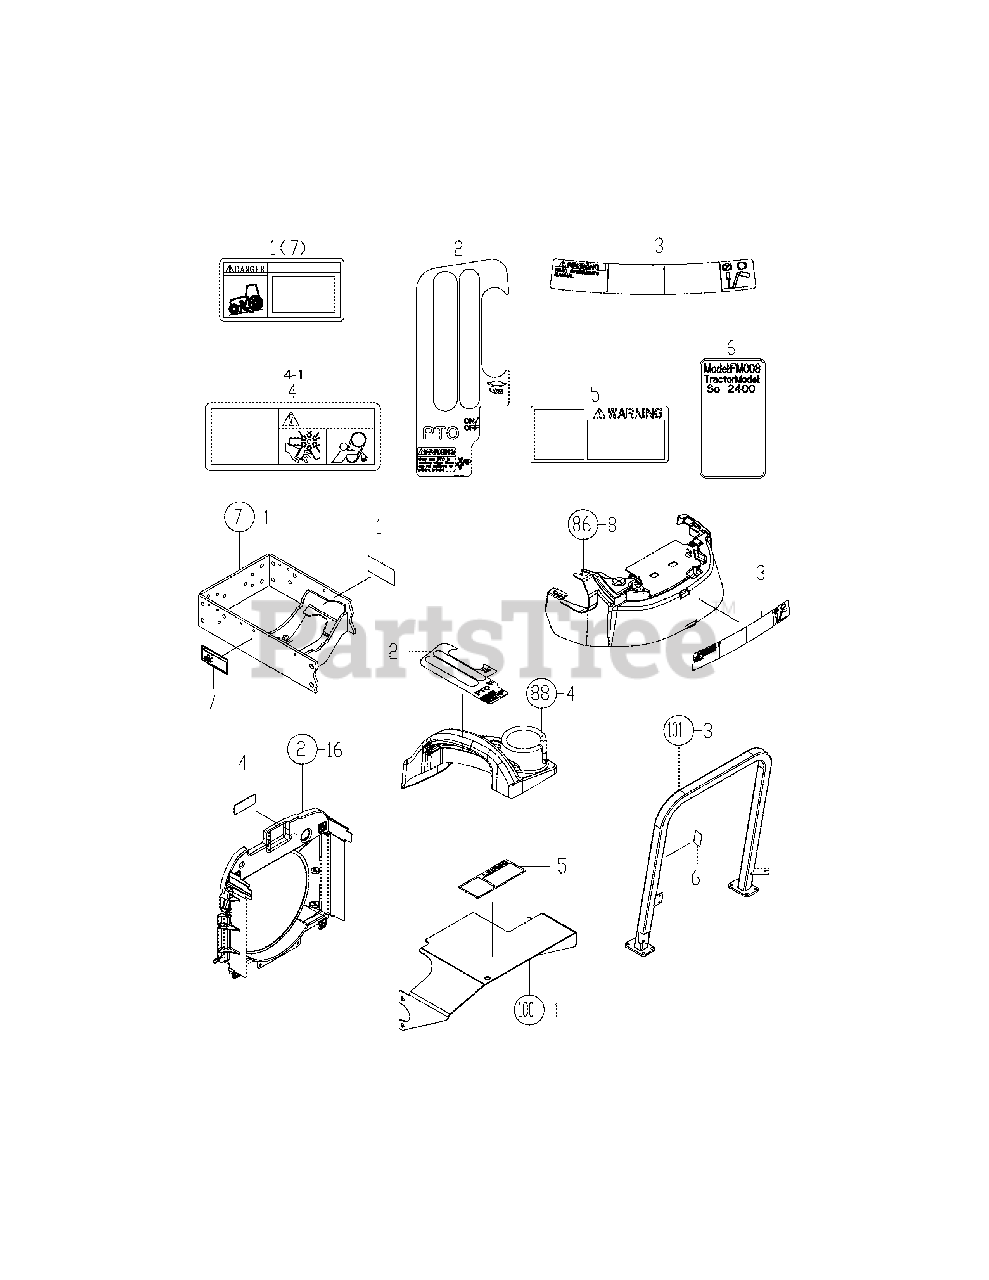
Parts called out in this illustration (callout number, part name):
1	Label, Danger, Start
2	Label, Leverguide L
3	Label, Caution, Genera
4	Label, Warning, Fan
4-1	Label, Warning, Fan
5	Label, Pto Warning
6	Label, Rops
7	Label, Warnibg, Stop
